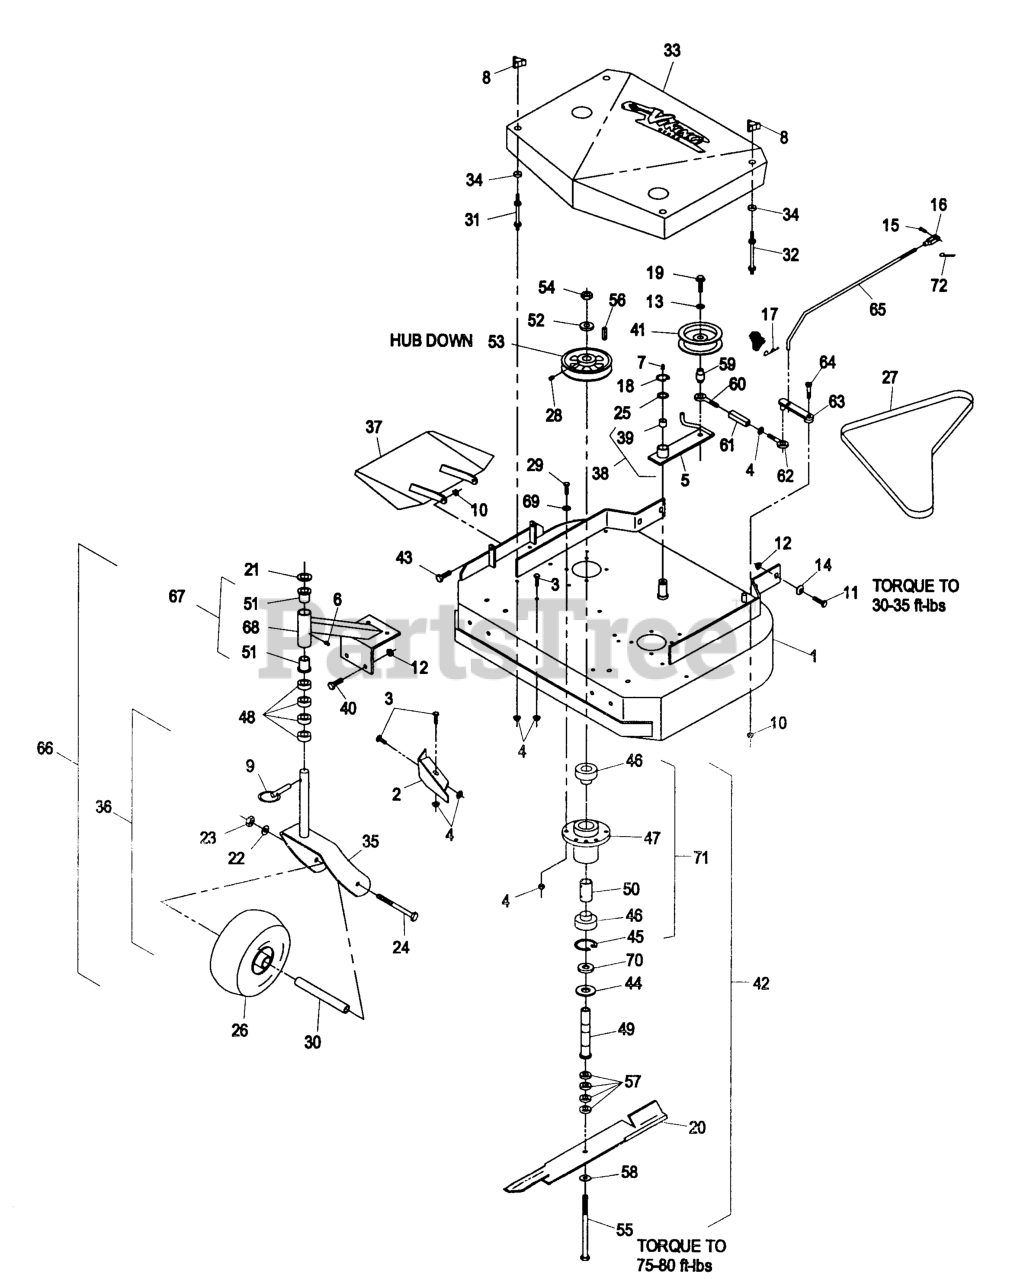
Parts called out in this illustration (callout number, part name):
2	BAFFLE-DOGLEG
8	KNOB-3 PRONG
15	PIN-CLEVIS
16	YOKE-ADJUSTABLE
17	PIN-COTTER
21	WASHER-FLAT
25	WASHER-SPINDLE
27	BELT,DECK DRIVE
28	SCREW-SET
31	STUD-SHIELD, BELT (SHORT)
32	STUD-SHIELD, BELT (LONG)
37	Chute
39	BEARING,POWDERED METAL
42	HOUSING,CUTTER COMPLETE(S
44	GUARD-BEARING, BOTTOM
46	BEARING
48	SPACER-CASTER
49	TUBE-SPINDLE, SHORT
50	SPACER-BEARING
51	BEARING-FLANGED
52	WASHER-RETAINER, SHEAVE
55	SCREW-CAP, HH
58	WASHER-SPRING
59	BUSHING-ENGAGEMENT
60	EYEBOLT-THREAD, LH
61	BODY-TURNBUCKLE
62	EYEBOLT-THREAD, RH
64	BOLT,SHLDR KSKH
65	ARM-LINKAGE, ASSIST
66	CASTER/MOUNT ASM
67	SUPPORT ASM
69	WASHER-SPRING
70	SPACER-PULLEY/BEARING
